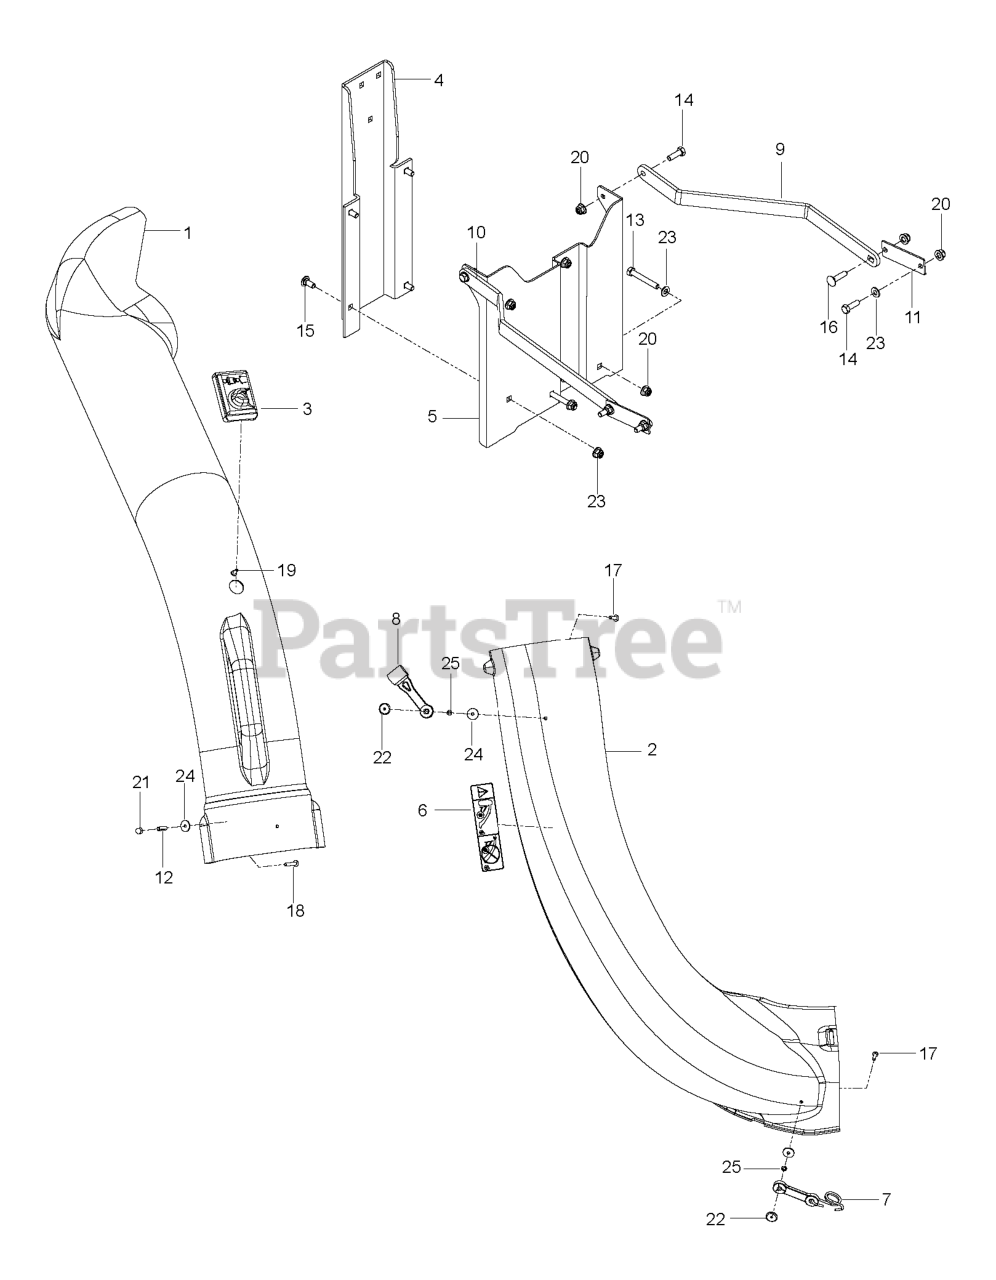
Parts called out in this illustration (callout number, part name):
1	UPPER CHUTE
2	CHUTE.LOWER.LT.46"
3	DUMP BAG INDICATOR
4	BRACKET, COLLECTION BLK
5	MOUNT, 2 BIN COLLECT, BLK
6	DECAL, CATCHER
7	LATCH ASSY TBR
8	HOOD LATCH
9	STRAP, SUPPORT, RT BLK
10	STRAP, SUPPORT, LT BLK
11	REINFORCEMENT PLATE BLK
12	BSHG .202X.75 LG SPLIT ZD SPEC
13	BOLT.FIN HEX 5/16-18UNC X2 1/4
14	BOLT.FIN.HEX.5/16-18UNC X 1.00
15	RP BOLT 5/16-18 X3/4 ZN/YEL GR
16	BOLT, CARRIAGE 5/16X1-1/4
17	SCREW
18	SCREW
20	5/16-18 NYLOC FLANGE NUT
21	NUT 10-24 ACORN ZD
22	NUT 10-24 WELD PLATED
23	WASHER
25	WASHER - 3/16 LOCK ZD
